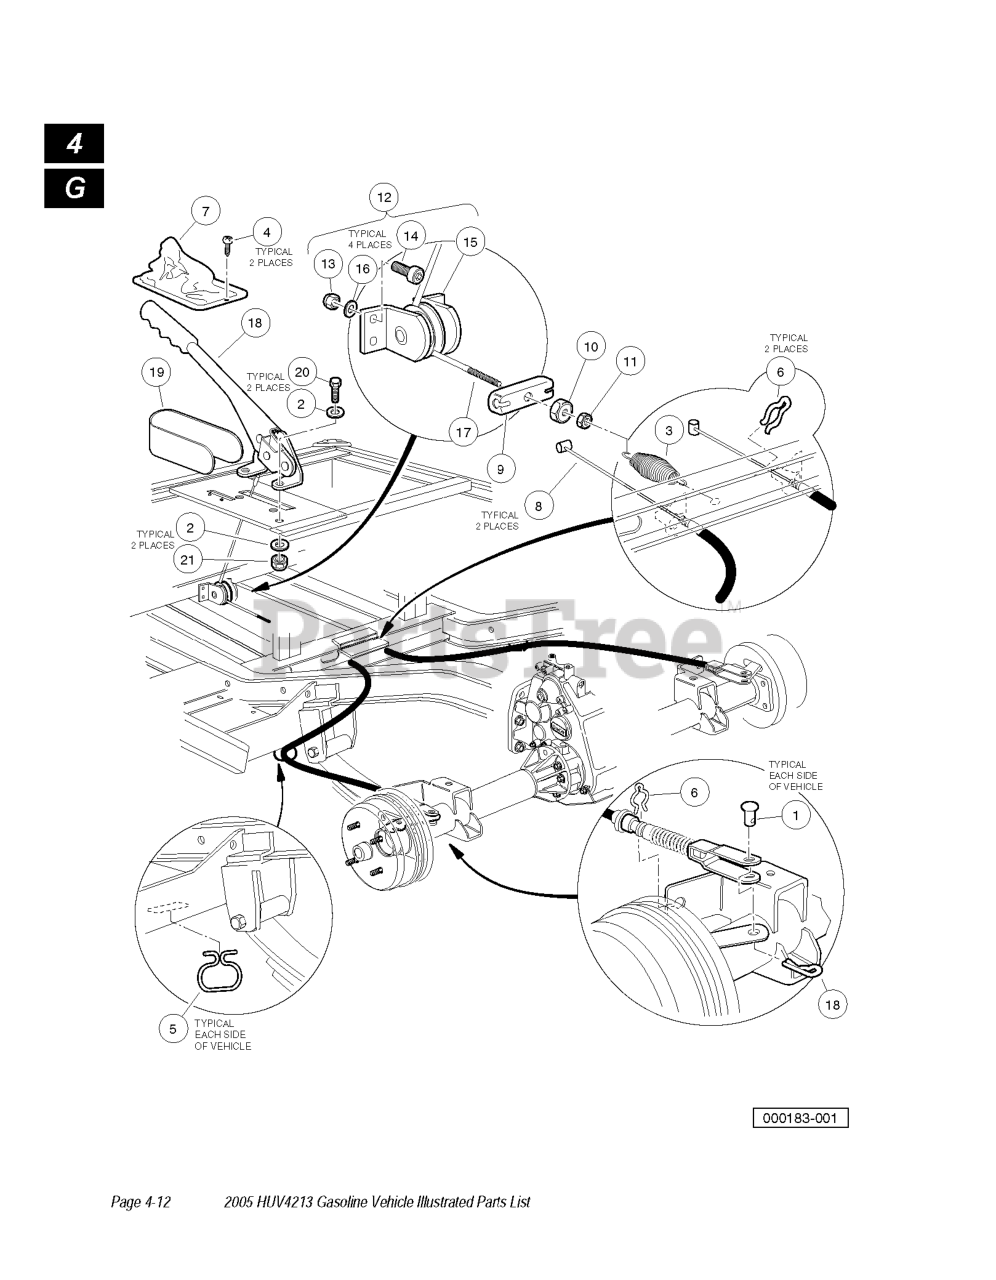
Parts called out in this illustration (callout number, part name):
2	WASHER, 3/8 FLAT
3	SPRING, BRAKE RETURN
4	SCREW, #7-19 X .625 PHL PN TAP
5	HANGER, BRAKE CABLE, LG
6	PARK BRAKE CABLE CLIP
7	PARK BRAKE BOOT
8	CABLE, LONG PARKING BRAKE
10	NUT, 5/16-24 HEX CONE
12	PULLEY KIT
14	SCREW, #10-24 X 3/4 SOCKET HD
15	2" FLAT MOUNT PULLEY
16	WASHER FLAT
17	PARK BRAKE CABLE, CTR
18	HANDLEVER, BOX CONFIG
19	HANDLEVER, BOX CONFIG
22	LOCKNUT, 3/8-16 HEX
